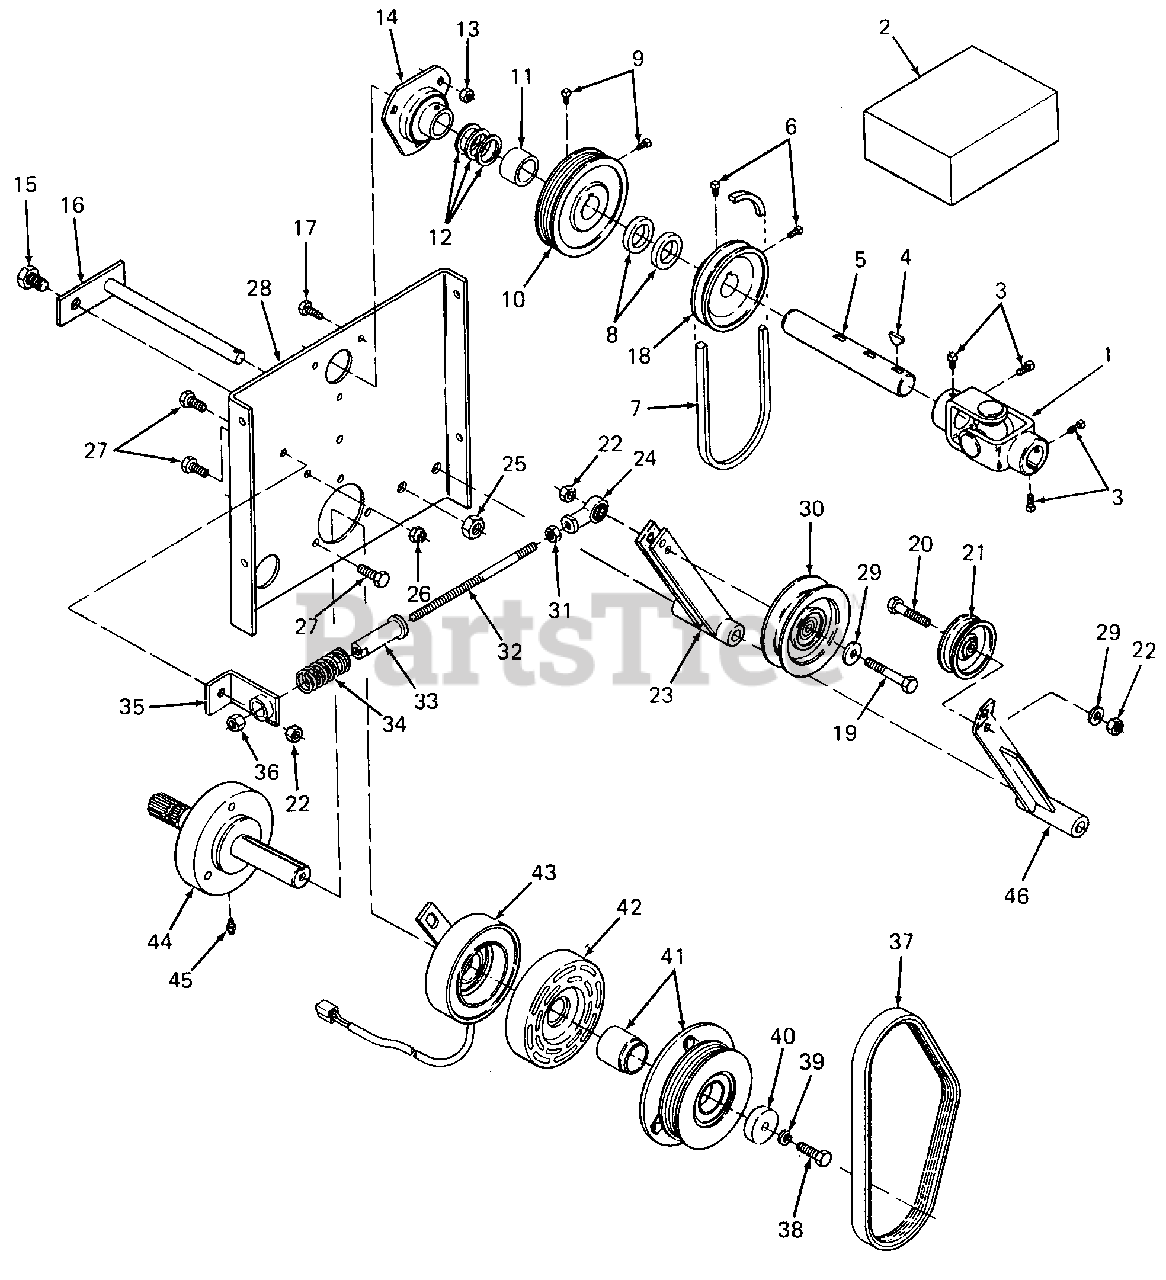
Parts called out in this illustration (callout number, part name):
1	Coupling, Engine
2	Kit, U-Joint
3	Setscrew, 3/8-16 X .50 Cup
4	Key, Woodruff, Hi-Pro
5	Shaft, Line
6	Setscrew, 5/16-18 X .50 Cup
7	Belt, Primary Drive
9	Setscrew, 5/16-18 x 5/8
10	Pulley, PTO
11	Spacer, Line Shaft
12	Race, Thrust, .060 Thk
13	Nut, Hex Center Lock, 5/16-18
14	Bearing, Flangette
15	Screw, Hex Cap, 1/2-13 X 1.0 Lg
16	Pin Assy, Idler Roller
17	Bolt, Carriage, 5/16-18 X 1.0 Lg
19	Screw, Hex Cap, 3/8-16 x 2.25 Lg
20	Screw, Hex Cap, 3/8-16 x 1.75 Lg GR5
21	Pulley, Idler - Primary
22	Nut, Hex Center Lock, 3/8-16
23	Arm, PTO Idler
24	Rod End, Female, 3/8-24
25	Nut, Hex Center Lock, 1/2-13
26	Nut, Hex Center Lock Jam, 3/8-16
27	Screw, Hex Cap, 3/8-16 x 1.0 Lg GR5
28	Plate, PTO Mounting
29	Washer, Flat, .385 X .87 X .06 Thk
30	Pulley, Idler (PTO)
31	Nut, Hex Jam, 3/8-24
32	Rod, Idler (PTO)
33	Adjuster, PTO
35	Bracket, PTO Spring
36	Nut, Hex Center Lock, 3/8-16
37	Belt, Poly-V
38	Screw, Hex Cap, 7/16-20 X 1.50 Lg GR5
39	Washer, Lock, 7/16
40	Washer, Electric Clutch, .250 Thk
41	Armature w/Hub
44	PTO Shaft/Housing
45	Fitting, Grease
46	Arm, Primary Idler
